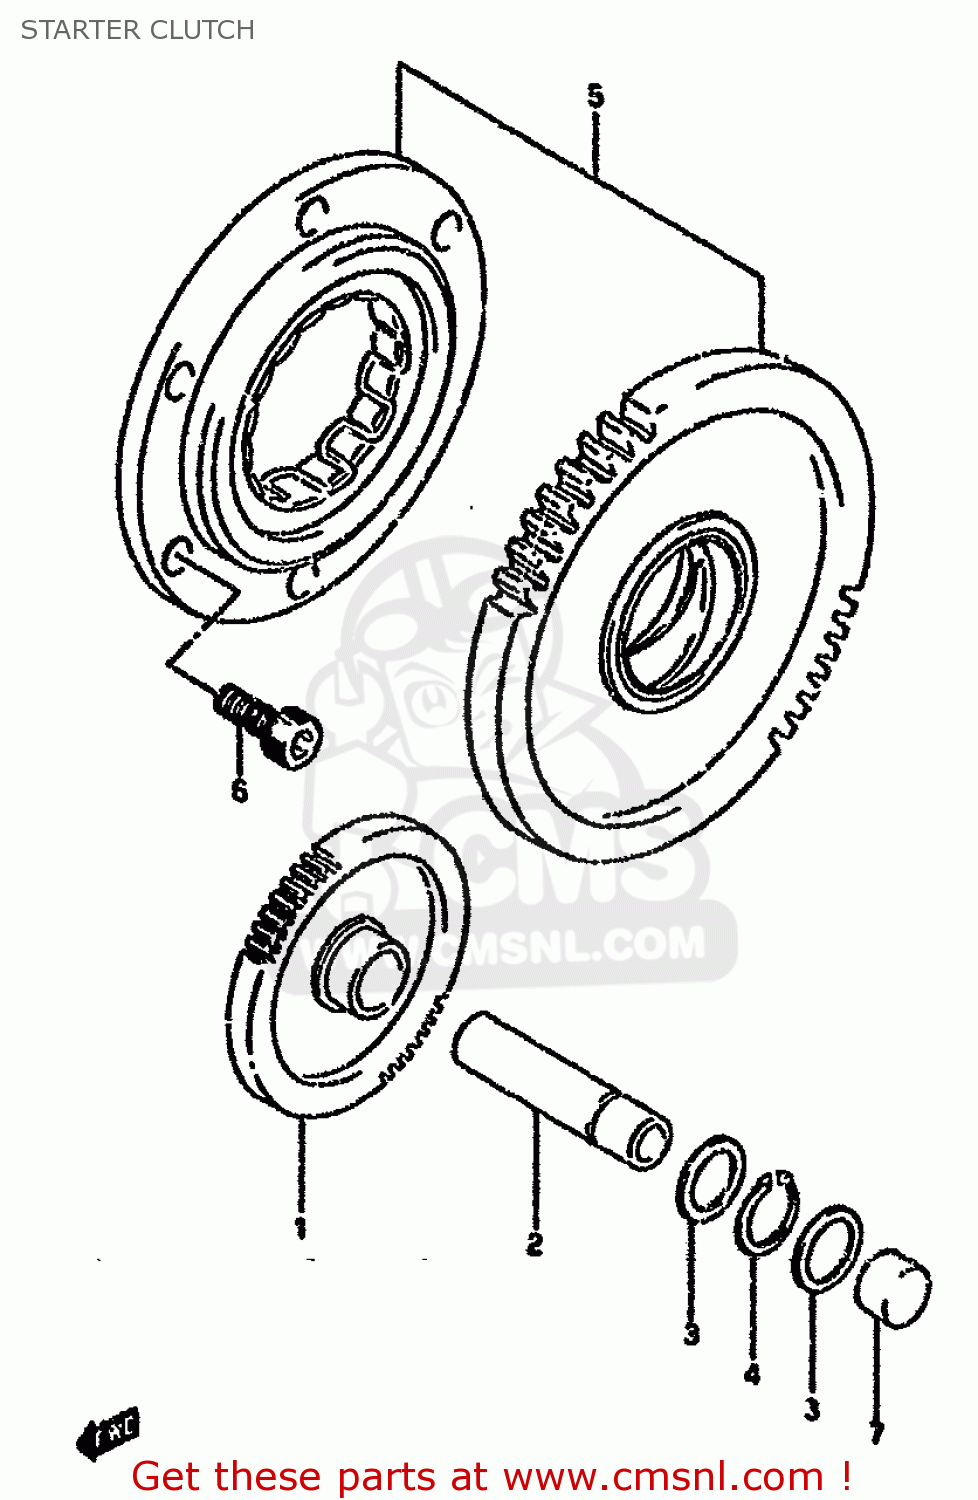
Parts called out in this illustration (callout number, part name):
1	GEAR,STARTER IDLE
2	SHAFT,STARTER IDLE GEAR
3	WASHER
4	CIRCLIP,12 MM
5	CLUTCH SET,STARTER
6	BOLT
7	PLUG
